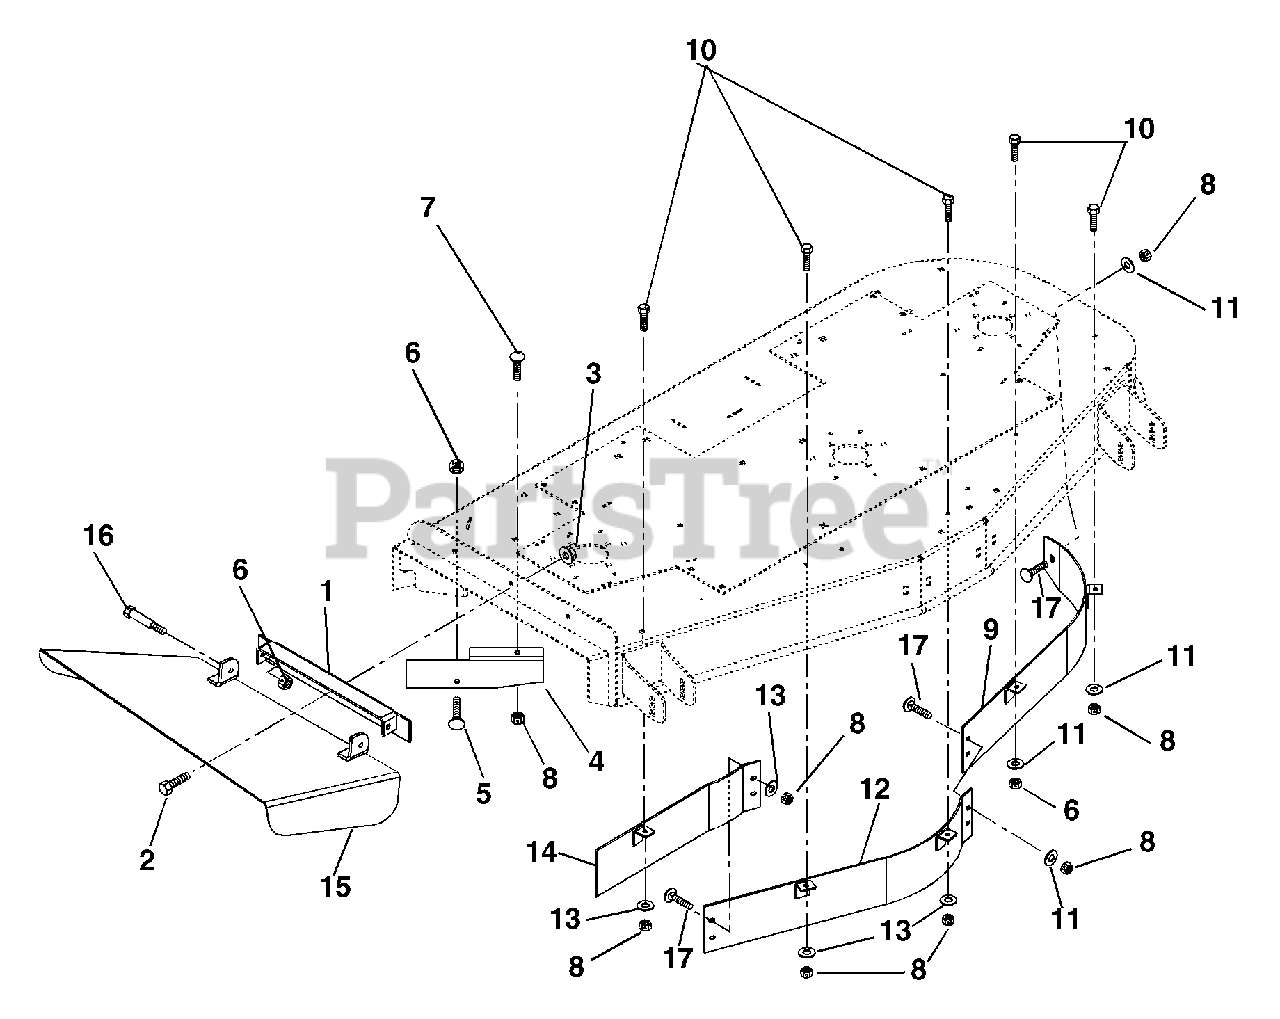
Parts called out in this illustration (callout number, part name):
1	Weldment, Discharge Chute Bracket
2	Bolt-Hex .38-16 x 1.00 Grade 5
3	Nut-Locking-Flange .38-16
4	Deflector, 72"
5	Bolt-Round Head Square Neck .38-16 x 1.00 Grade 2
6	Nut-Locking-Center .38-16
7	Bolt-Round Head Square Neck .31-18 x 1.00 Grade 5
8	Nut-Locking-Nylon .31-18
9	Weldment, 72" Left Hand Baffle
10	Bolt-Hex .31-18 x 1.00 Grade 5
11	Washer-Flat-Steel .312 x .734 x .065
12	Weldment, 72" Center Baffle
13	Washer-Flat-Steel .312 x .734 x .065
14	Weldment, 72" Right Hand Baffle
15	Weldment, Discharge Chute 72"
16	Bolt-Shoulder .38-16 x .38
17	Bolt-Round Head Square Neck .31-18 x .75 Grade 2
18	72" S.D. Mulch Kit
19	72" Discharge Cover Kit
